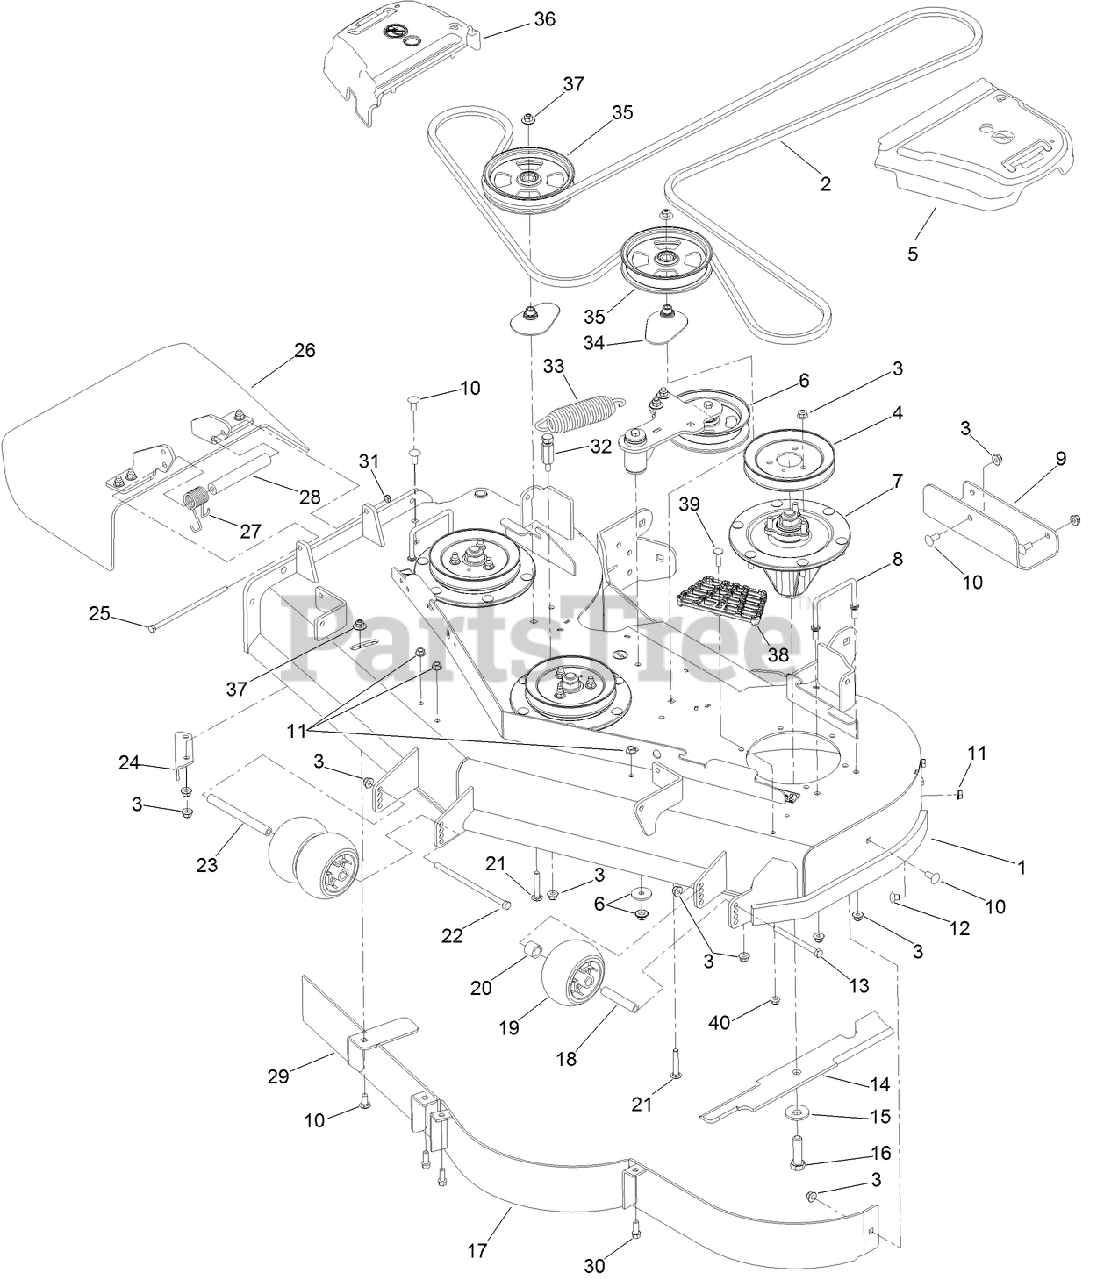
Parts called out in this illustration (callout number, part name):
1	DECK DECAL ASM
2	BELT-V
3	NUT-HF, NI
4	PULLEY
5	COVER-BELT, LH
6	IDLER ARM ASM
7	SPINDLE ASM
8	WIREFORM-COVER
9	PLATE-SKID
10	SCREW-CARR
11	NUT-HHF, WHIZ
12	SCREW-CARR
13	SCREW-HH
14	BLADE-18IN, HI FLOW
15	WASHER-BLADE BOLT, HEAVY
16	SCREW-BLADE
17	BAFFLE ASM
18	TUBE-SPANNER
19	ROLLER-SCALP, ANTI
20	TUBE-SPACER
21	BOLT-CARR, SHORT NECK
22	SCREW-HH
23	SPACER-WHEEL
24	BAFFLE-DISCHARGE
25	SCREW-HH
26	RUBBER DEFLECTOR ASM
27	SPRING-TORSION
28	SPACER
29	BAFFLE ASM
31	NUT-LOCK, NI
32	ANCHOR-SPRING, TALL
33	SPRING-EXTENSION
34	SPACER-PULLEY
35	PULLEY-IDLER, FLAT
36	COVER-BELT, RH
37	NUT-FLANGE, NI
38	STEP-DECK
39	SCREW-CARR
40	NUT-HF, NI
